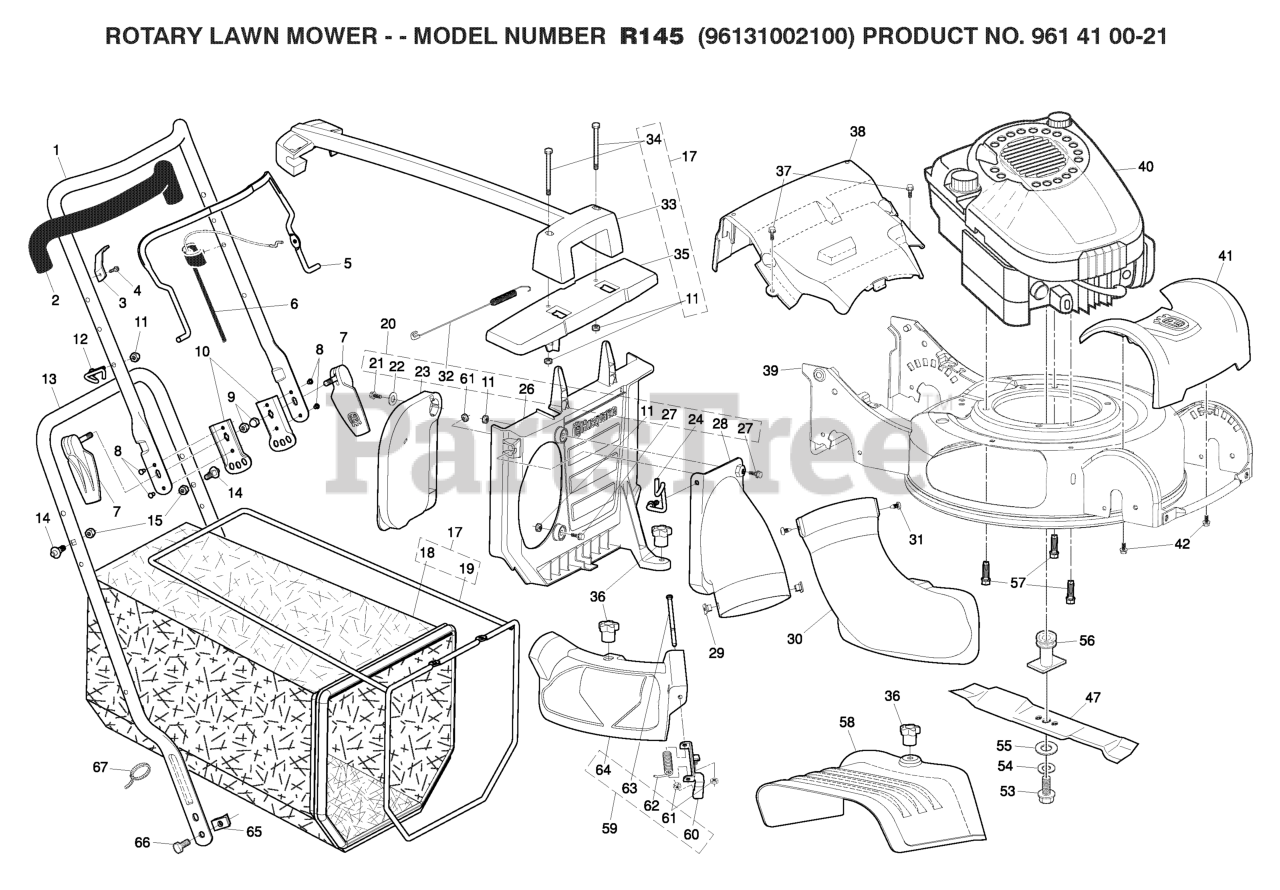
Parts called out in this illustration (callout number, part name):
2	GRIP, FOAM
3	BRACKET.UPSTOP
5	BAIL CONTROL
6	CABLE.MZR.50.SNAP-IN
7	ASM.QUICK.RELEASE
9	Locknut, Hex 1/4-20
10	BRACKET.ADJ.3POS.GREY
11	NUT
12	RB GUIDE.ROPE.STD.BLK.ZIN WSL
14	STUD.QUICK.ADJUST
15	NUT.LOCK.5/16-18
22	WASHER
26	BRACKET
27	BOLT, SHOULDER
31	SCREW T-30 1/4-20 X
36	KNOB.MULCH.DOOR
37	SCREW, HEX WASHER HEAD
42	SCREW.HWH.13-16-5.8.BZP
47	BLADE.SWEPT.WING.45CM.H.TREAT
53	BOLT.HD.HEAD.3/8-24X2.50 (2 2)
54	LOCKWASHER
55	WASHER,HARDEN
56	ADAPTER.BLADE.PUSH
57	BOLT 3/8-16X1-1/8
61	NUT.HEX.FLANGE.1/4
62	SPRING.MULCH.DOOR
63	ROD.HINGE.1/4"3.82"
64	DOOR.MULCH.GREY
67	TIE GUIDE
